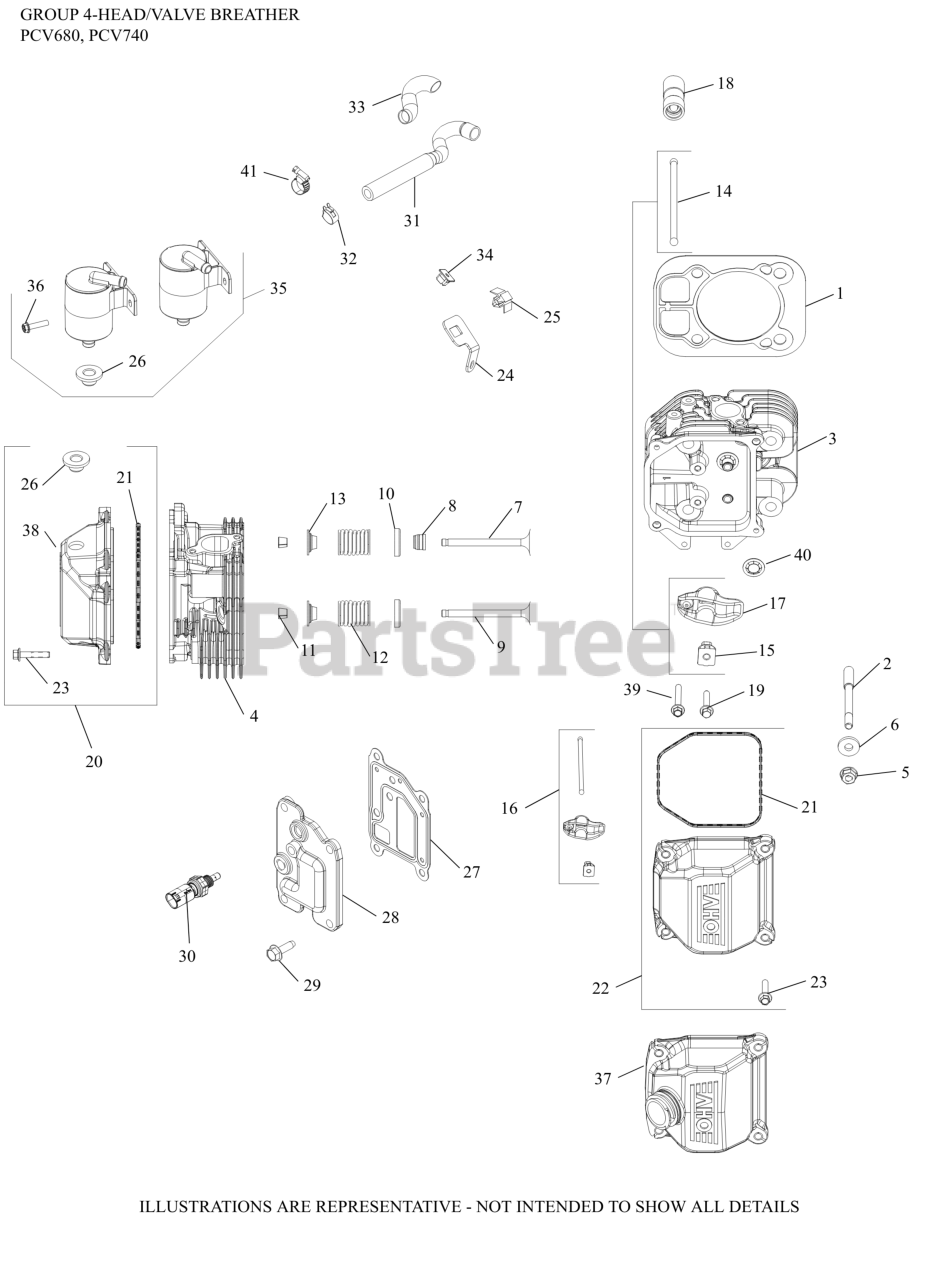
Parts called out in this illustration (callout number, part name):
1	KIT, GASKET CYLINDER HEAD
2	STUD, M8X1.25
3	KIT, CYLINDER HEAD (#1)
5	NUT, FLG M8X1.25
6	WASHER, FLAT 8.6 MM
7	VALVE, INTAKE (STD)
7	VALVE, INTAKE (.25)
8	SEAL, VALVE BAND
9	VALVE, EXHAUST
9	VALVE, EXHAUST (.25)
10	RETAINER, SPRING
11	KIT, RETAINER
12	SPRING, VALVE
13	CAP, VALVE SPRING
14	ROD, PUSH
15	PIVOT, ROCKER ARM
16	KIT, VALVE TRAIN
17	ARM, ROCKER
18	LIFTER, VALVE HYDRAULIC-USE 25 351 11-S
20	KIT, VALVE COVER
21	O-RING (YELLOW), VALVE CO
22	KIT, VALVE COVER-PLAIN (PLASTIC)
23	SCREW, FLG M6X1.0X30
24	BRACKET, OXYGEN SENSOR
25	CLIP, O2 SENSOR
26	GROMMET, RUBBER
27	GASKET, BREATHER
28	KIT, BREATHER COVER
29	SCREW, THREAD FORMING
30	SENSOR, TEMPERATURE
31	HOSE, BREATHER
33	SLEEVE, ANTI ABRASION-USE 25 431 12-S
34	NUT, PLASTIC
35	KIT, BREATHER SEPARATOR
39	SCREW, HEX FLANGE (SILVER) M6X1.0X45
40	RETAINER, VALVE GUIDE (KM)
NI	KIT, CYLINDER HEAD (#2)
